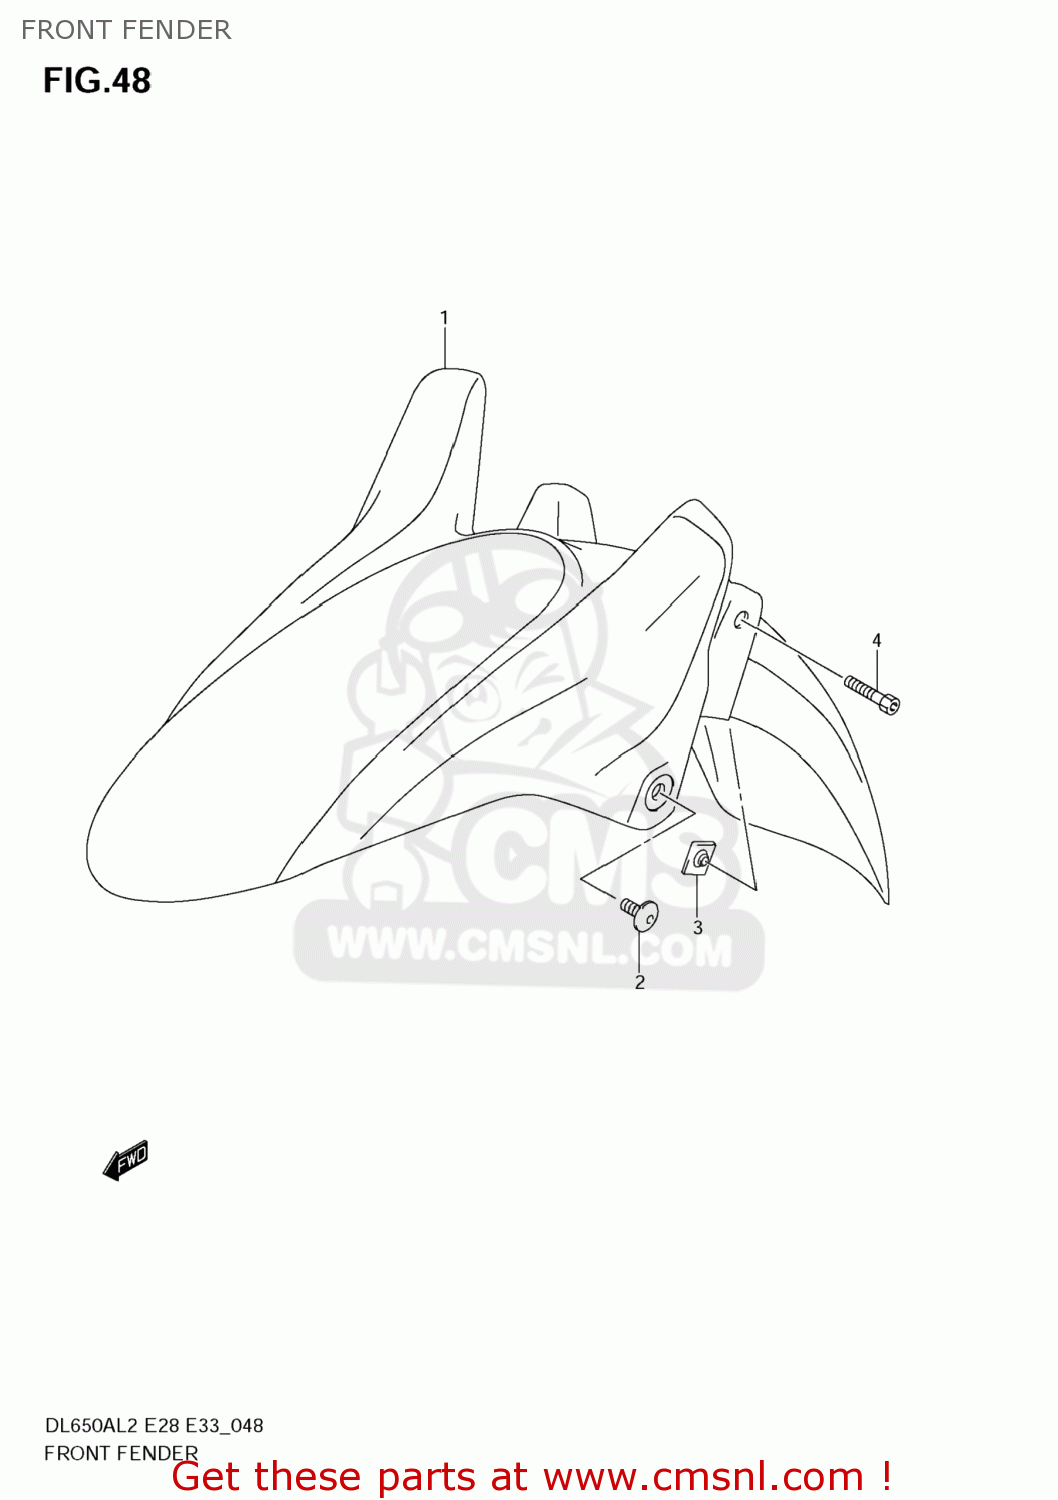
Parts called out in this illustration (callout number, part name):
1	FENDER,FRONT
2	SCREW(6X16)
3	NUT,FR FENDER
4	BOLT(6X30)
